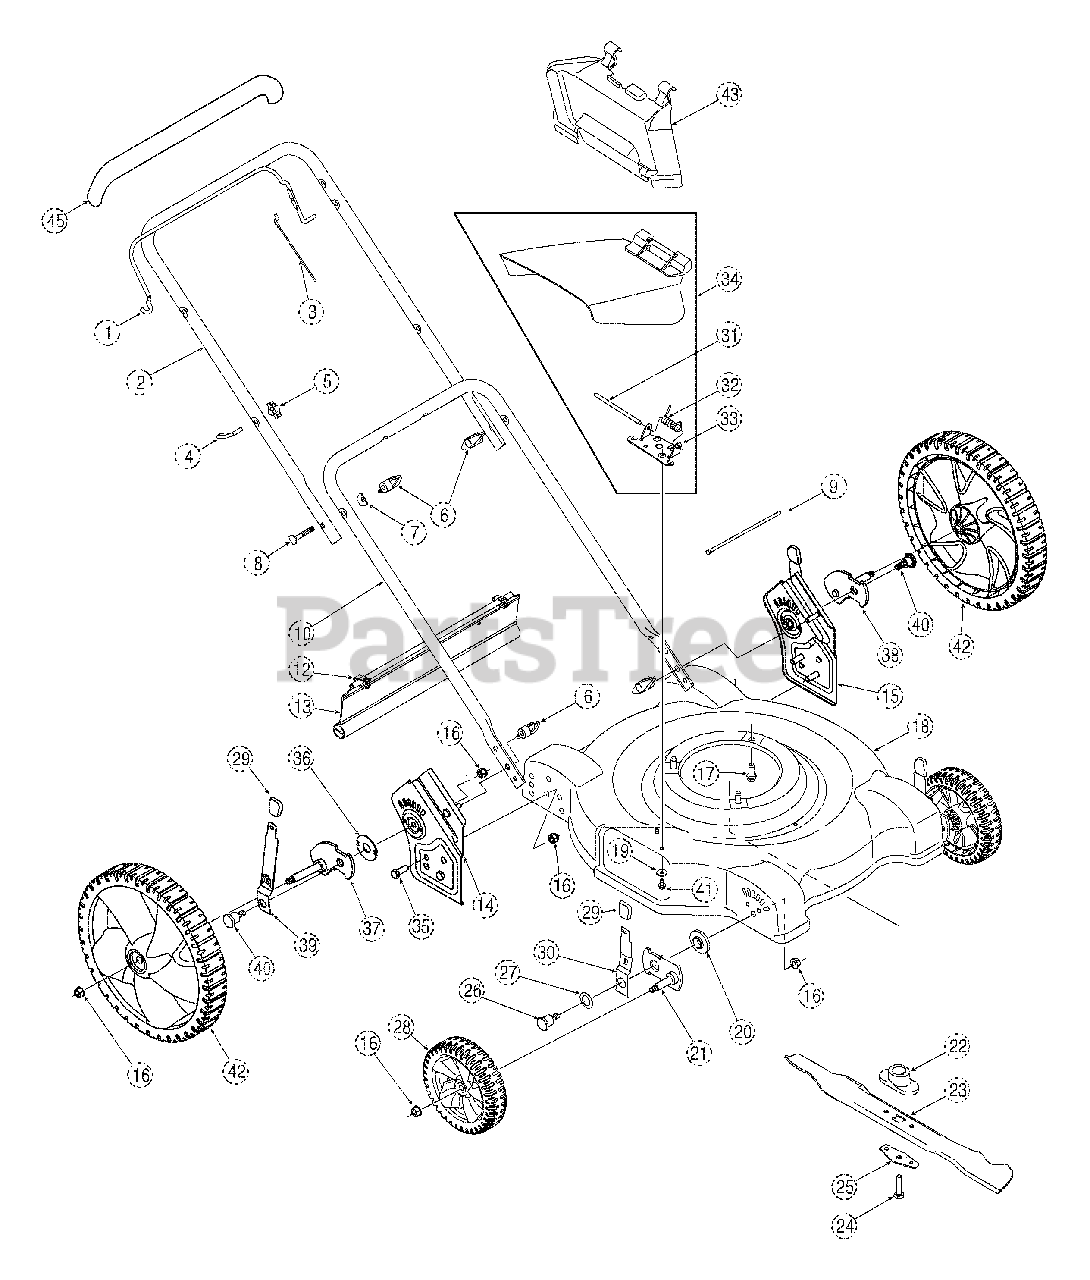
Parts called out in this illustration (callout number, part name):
3	Blade Control Cable - 48.25"
7	Shoulder Washer.320 ID x.93 OD
8	Carriage Bolt 5/16-18 x 2.0
12	Hinge Clip
13	Trail Shield
17	Hex Washer Screw 3/8-16 x 1.0
19	Bell Washer.265 x.75
20	Height Adjuster Bearing
21	Pivot Arm Assembly
22	Blade Adapter
23	22" Mulching Blade
24	Hex Cap Screw 3/8-24 x 1.5
25	Blade Bell Support
26	Shoulder Screw 3/8 - 16 x .302
27	Bell Washer.760 ID x 1.25 OD
28	Front Wheel Assembly 7 x 2.125
29	Height Adjuster Knob
30	Front Spring Lever
31	Hinge Pin
32	Torsion Spring
33	Deflector Chute Adapter
34	Side Discharge Chute Assembly
35	Hex Cap Screw 3/8-16 x .75
36	Thrust Bearing.688 ID x 1.94 OD
37	Rear Pivot Arm Assembly - RH
38	Rear Pivot Arm Assembly - LH
39	Rear Spring Lever
40	Shoulder Screw 3/8 - 16 x .442
41	Screw 1/4-20 x.50
42	Rear Wheel Assembly 12 x 2.125
43	Mulching Baffle
45	Deluxe Bail Cover
